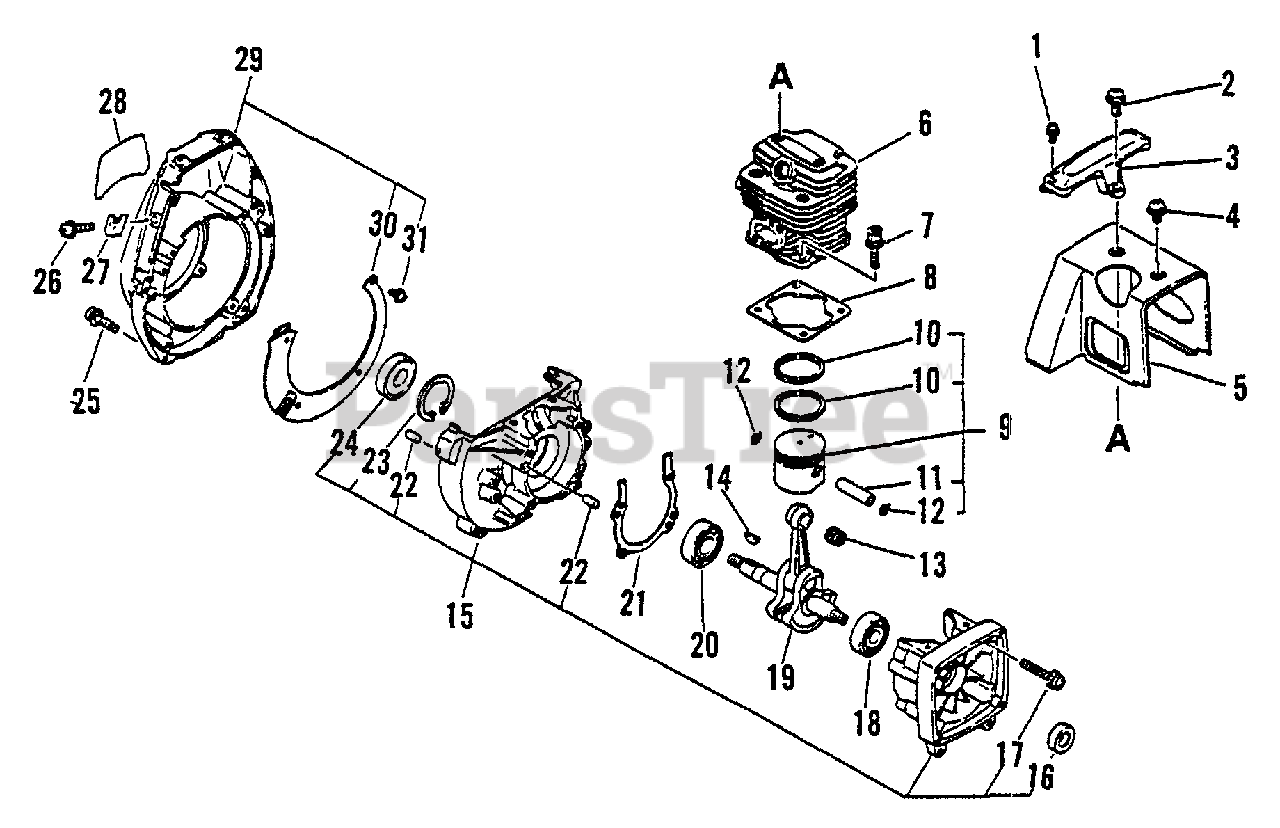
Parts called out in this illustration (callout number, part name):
1	SCREW 4×14
2	SCREW 5×16
3	GUARD, TOP
4	SCREW 5×10
5	COVER, ENGINE
6	CYLINDER
7	BOLT 5×20
8	GASKET, CYLINDER
9	PISTON KIT
10	RING, PISTON
11	PIN, PISTON
12	RING, RETAINING
13	BEARING, NEEDLE 9
15	CRANKCASE KIT
16	SEAL, OIL 12
17	SCREW 5×30
18	BEARING, BALL - 6201 C3
19	CRANKSHAFT
20	BEARING, BALL 6202
21	GASKET, CRANKCASE
22	PIN, LOCATING 5×10
23	RING, SNAP 35
24	SEAL, OIL
25	SCREW 5×25
26	SCREW 4×10
27	HOLDER, CABLE
29	FAN CASE ASSY
30	PLATE, GUIDE
31	SCREW 4×8
